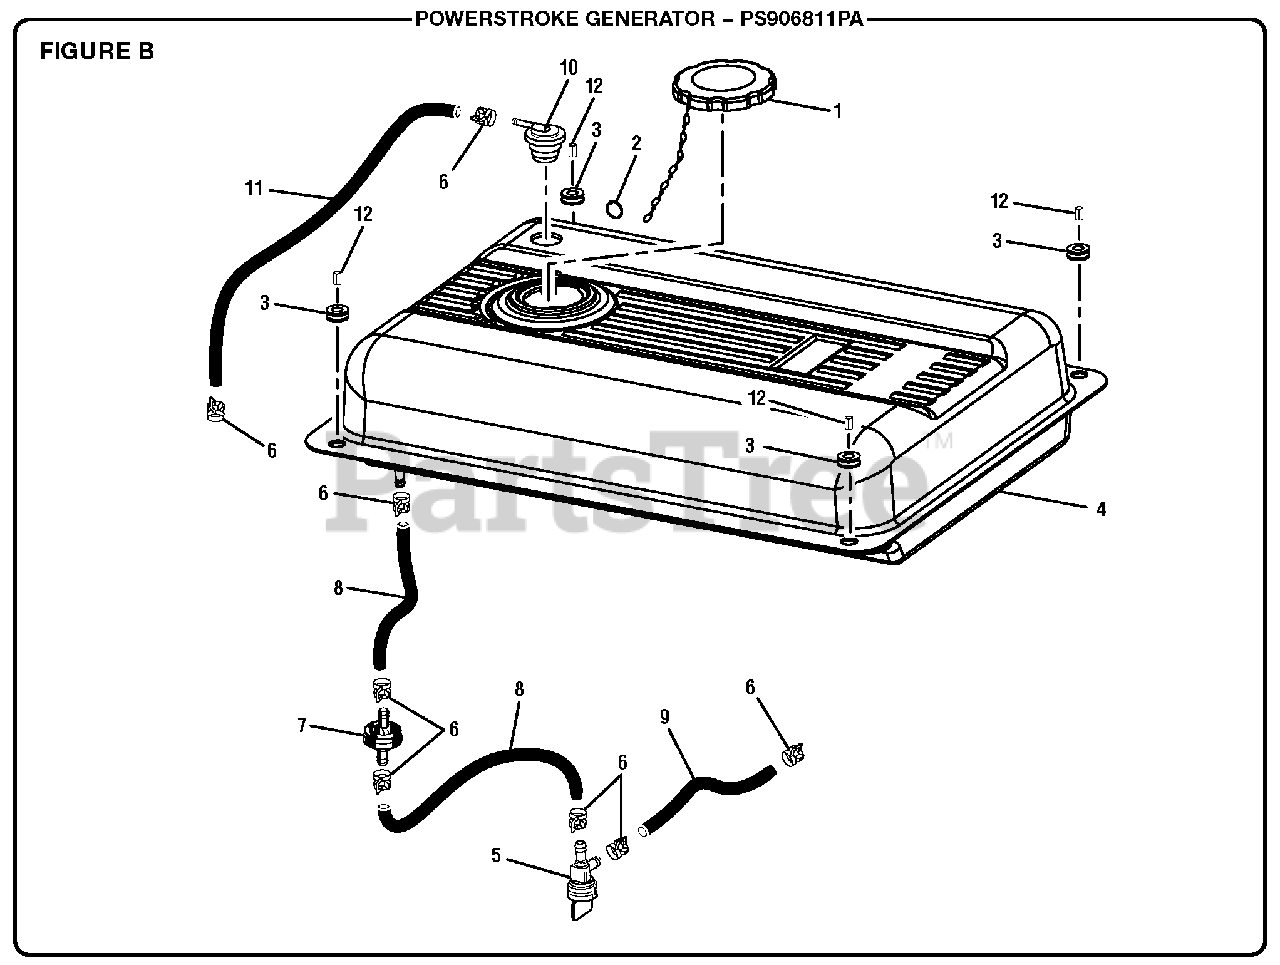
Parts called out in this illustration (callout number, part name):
1	Fuel Tank Cap
2	Ring Clip
3	Fuel Tank Insert
4	Fuel Tank Assembly
5	Fuel Valve
6	Fuel Line Clamp (1/2 in.)
7	Fuel Line Filter
8	Fuel Line (1/4 in.)
9	Fuel Hose (5 mm)
10	Vapor Vent
11	Vapor Hose
12	Fuel Tank Isolator (12 mm Dia.)
